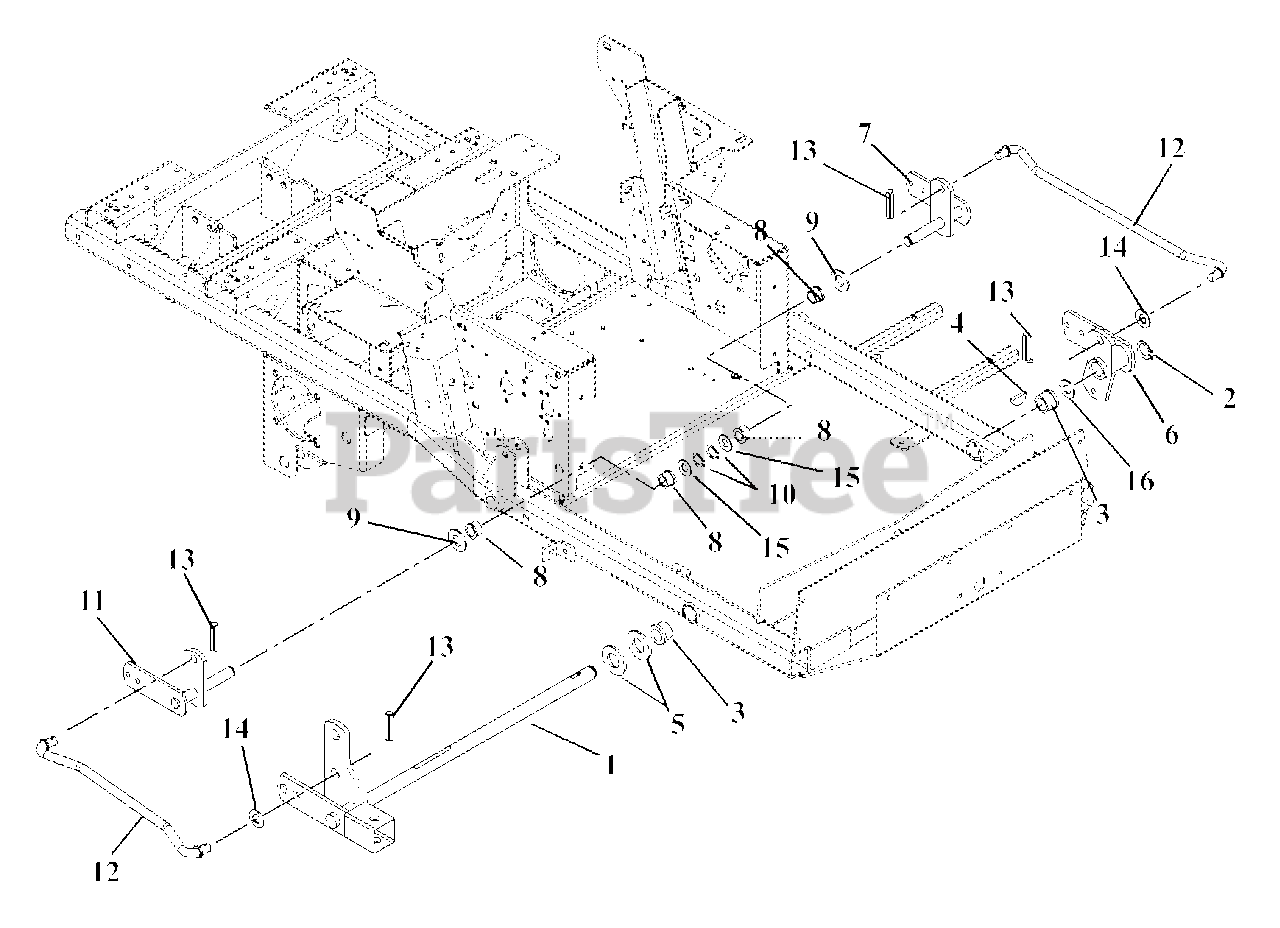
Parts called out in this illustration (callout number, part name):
1	WMT, FRONT MOWER LIFT (HYD)
2	RG-RTNG-EXT 1.00X.078
3	BSHG-FLG1.020X1.385X.75X1.75NY
4	KEY-WDRF .25X1.00 HRD #15
5	WSHR-FL-STL 1.063X2.00X.134
6	WMT, LH FRONT MOWER LIFT
7	WMT-LH REAR LIFT ARM (DIESEL)
8	BSHG-FLG .762X1.0X.580X1.48 NY
9	WSHR-HDND-THRST .758X1.23X.031
10	RG-RTNG-EXT .689X.078
11	WMT-RH REAR LIFT ARM (DIESEL)
12	ROD, LIFT ASSIST 19.35"
13	PIN-ROLL .250X1.25 STNLESS STL
14	WSHR-FL-STL .630X1.250X.062 YZ
15	WSHR-FL-STL .755X1.25X.125 YZ
16	WSHR-HDND-THRUST 1.00X1.55X.03
